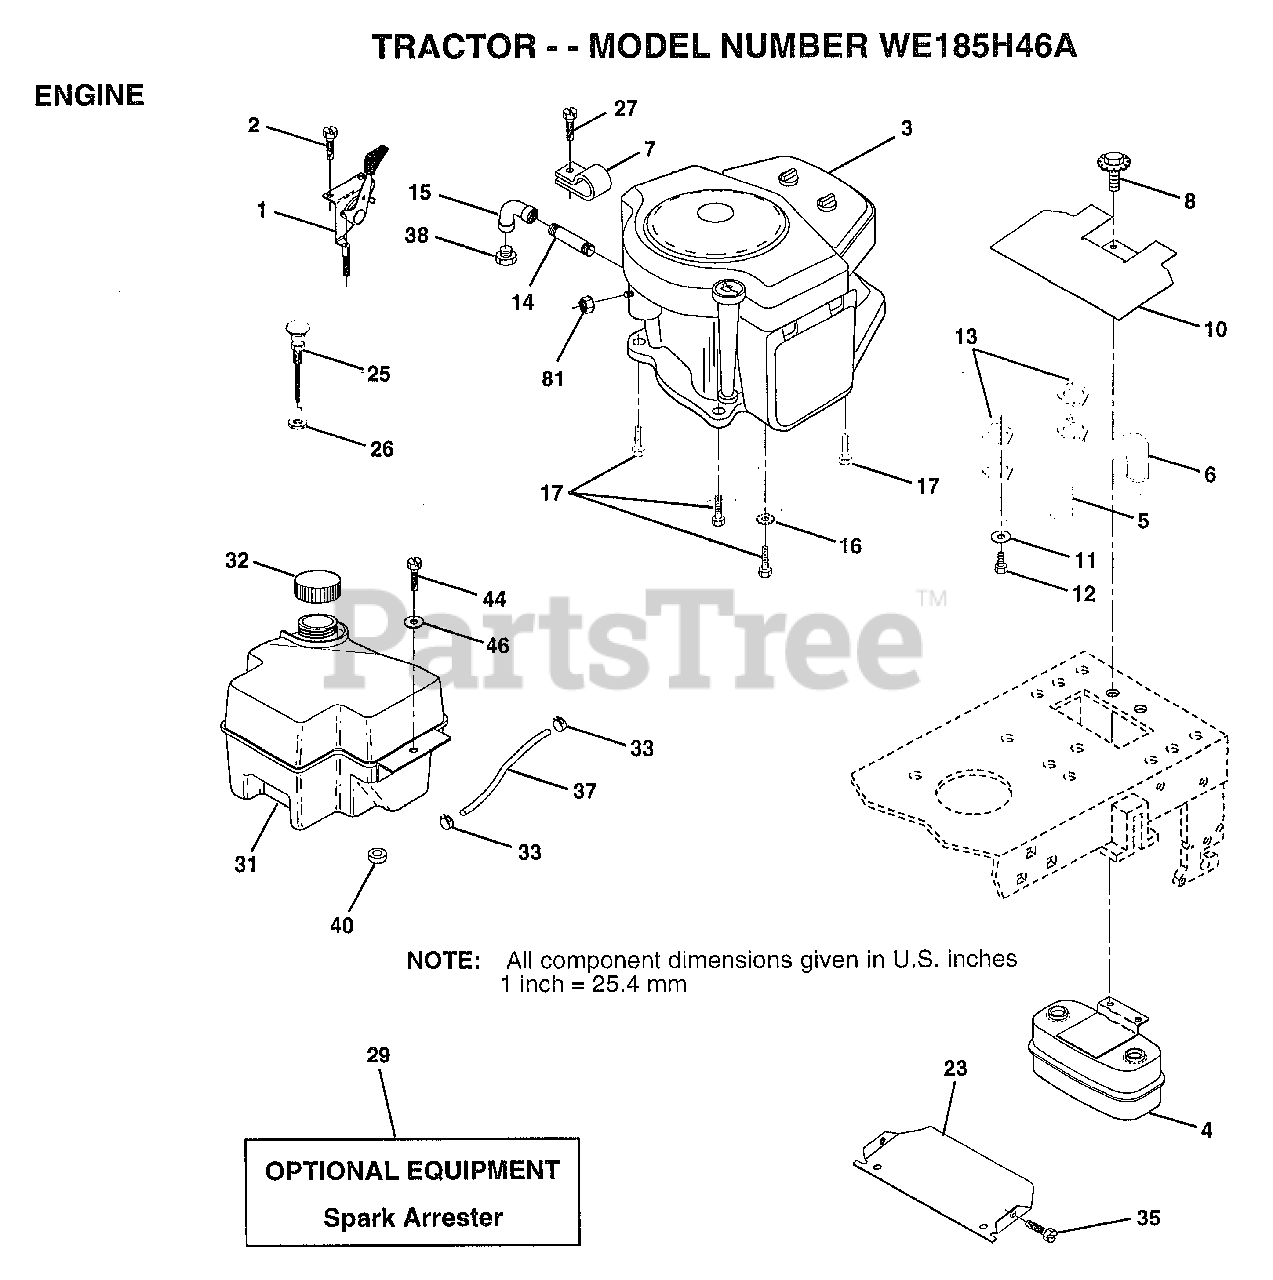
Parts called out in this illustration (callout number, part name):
1	CONTROL THRT 35.5
2	SCREW LT
4	MUFFLER.TW.LOTONE
5	EXHAUST.B&S.18.LH
6	EXHAUST.B&S.18.RH
7	CLAMP.TUBE.DBL.EN
8	BOLT.5/16-18.UNC
10	SHIELD.HEAT.
11	LOCKWASHER
13	GASKET MUFFLER
14	PIPE NIPPLE LT
15	ELBOW
16	LOCKWASHER
17	SCREW LT
23	SHIELD.BRN/DBR.GD
25	CONTROL.CHOKE.37
26	"NUT,KEPS 3/8-24IM"
27	"SCREW-TT,10-32 FL"
31	TANK.FUEL.FRONT.
32	CAP ASM FUEL
33	HOSE CLAMP
35	SCREW
37	LINE FUEL
44	SCREW HEX CRT
46	WASHER
81	NUT
